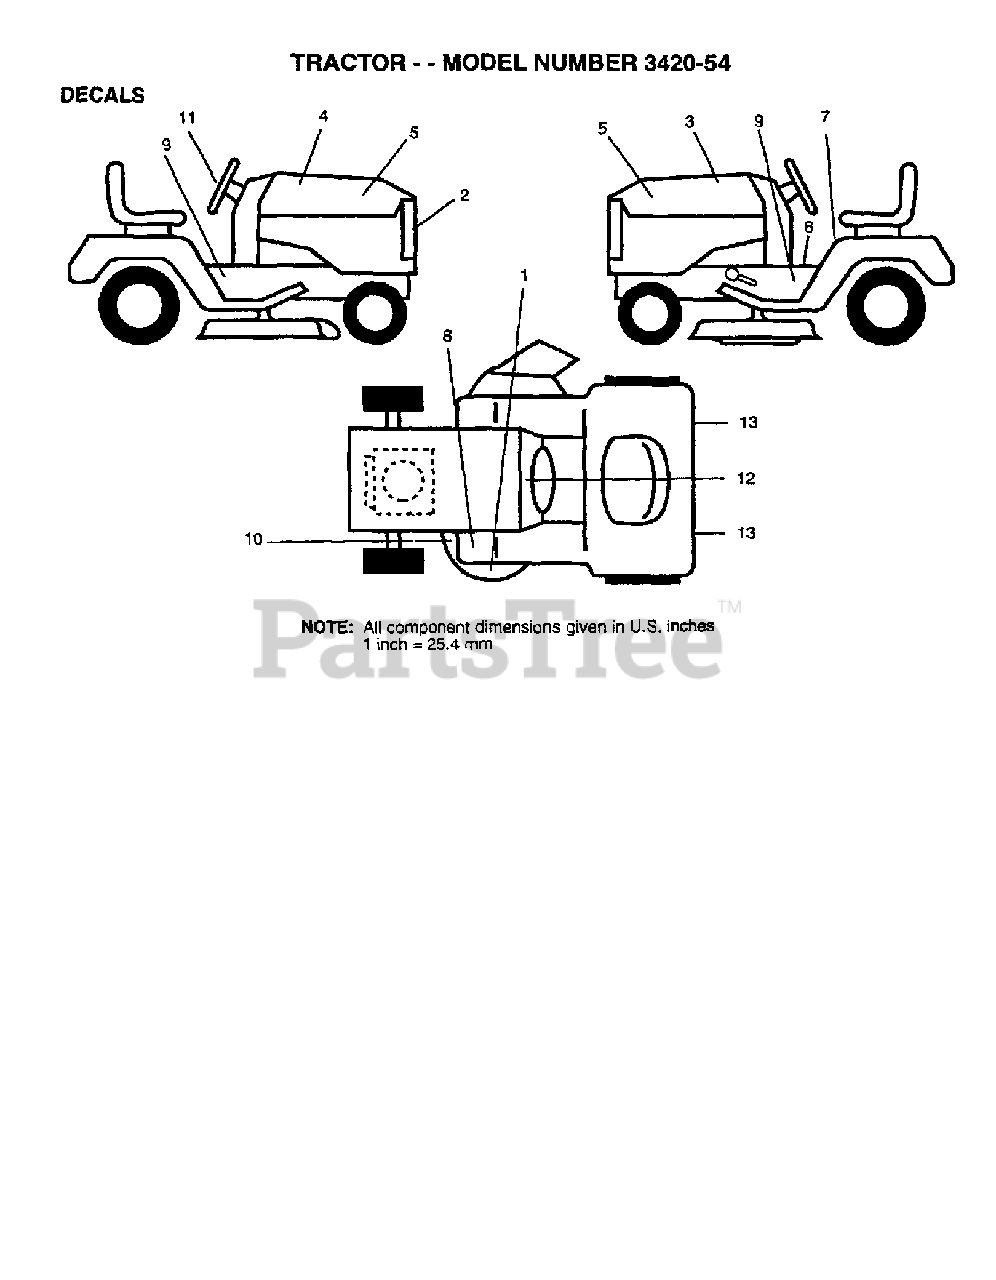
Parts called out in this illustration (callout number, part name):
2	Poulan TBD
3	Poulan TBD
4	Poulan TBD
5	Poulan TBD
6	DECAL PARK BRAKE
7	DECAL LT
9	Poulan TBD
10	DECAL V-BELT SCHEMATIC
11	Poulan TBD
13	REFLECTOR-TAIL YT
